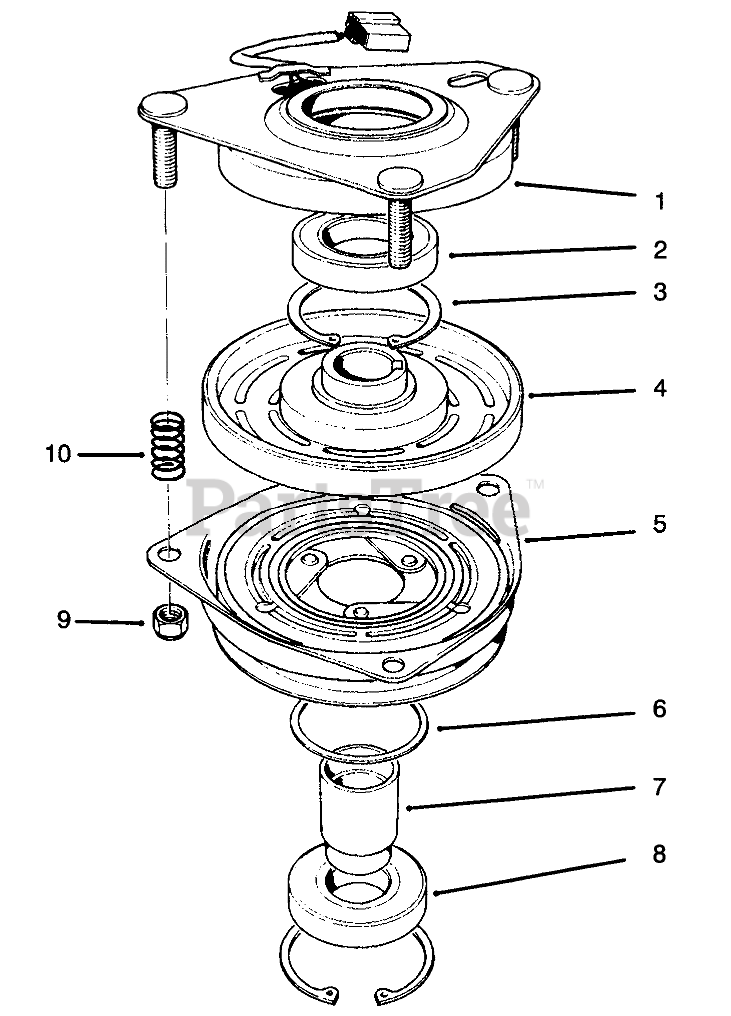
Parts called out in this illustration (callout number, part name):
1	Field Ass-y (Incl. Ref. #2 & 3)
2	BEARING-FIELD
3	RING-RETAINING
4	Field Coil, Rotor & Bearing Assembly (Incl. Ref. #1)
5	Armature & Pulley Assembly (Incl. Ref. #3, 6, 7, & 8)
6	SPACER-BEARING, PULLEY
7	COLLAR-BEARING
8	BEARING-PULLEY
9	NUT-HEX
10	SPRING
